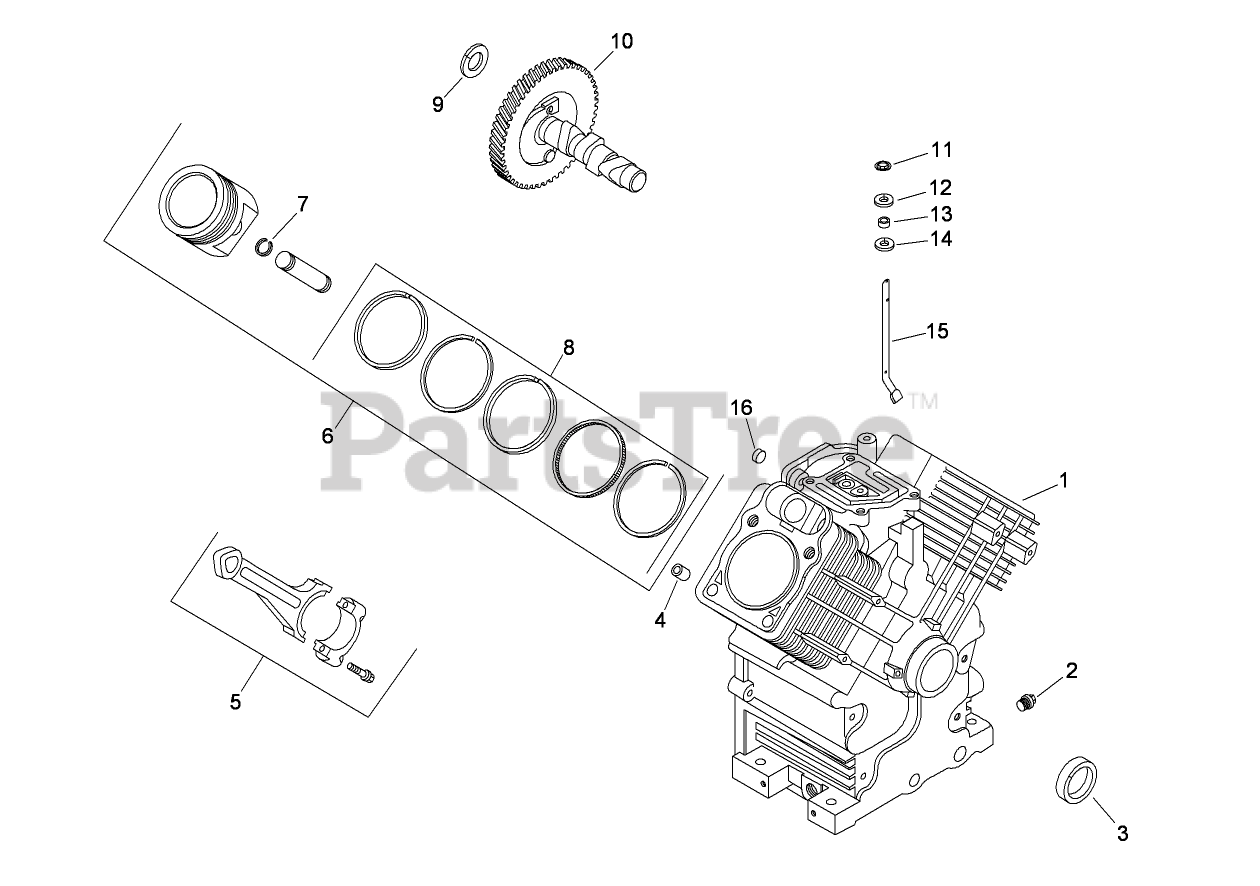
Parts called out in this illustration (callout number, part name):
1	Block-Cylinder (Short Block Replacement)
1	Block-Cylinder (Miniblock Replacement)
2	PLUG-PIPE HEAD, 3/8
3	SEAL-OIL (HELIX LIP)
4	PIN-LOCATING
5	ROD-CONNECTING (STD)
5	ROD-CONNECTING (.25)
6	Piston ASM (Std)
6	Piston ASM (.08)
7	Piston ASM (.25)
7	Piston ASM (.50)
7	RETAINER-PIN, PISTON
8	Ring Set (STD)
8	Ring Set (.08)
8	Ring Set (.25)
8	Ring Set (.50)
9	SHIM-CAMSHAFT (RED .032)
9	SHIM-CAMSHAFT (BLACK .04)
9	SHIM-CAMSHAFT (WHITE .028)
9	SHIM-CAMSHAFT (BLUE .03)
9	SHIM-CAMSHAFT (YELLOW .034)
9	SHIM-CAMSHAFT (GREEN .036)
9	SHIM-CAMSHAFT (GRAY .038)
10	Camshaft Kit
11	RETAINER-RING
12	WASHER-FLAT (9MM)
13	SEAL-CROSS SHAFT, GOVERNOR
14	WASHER-FLAT (11/32)
15	SHAFT-CROSS, GOVERNOR
16	PLUG-CUP
